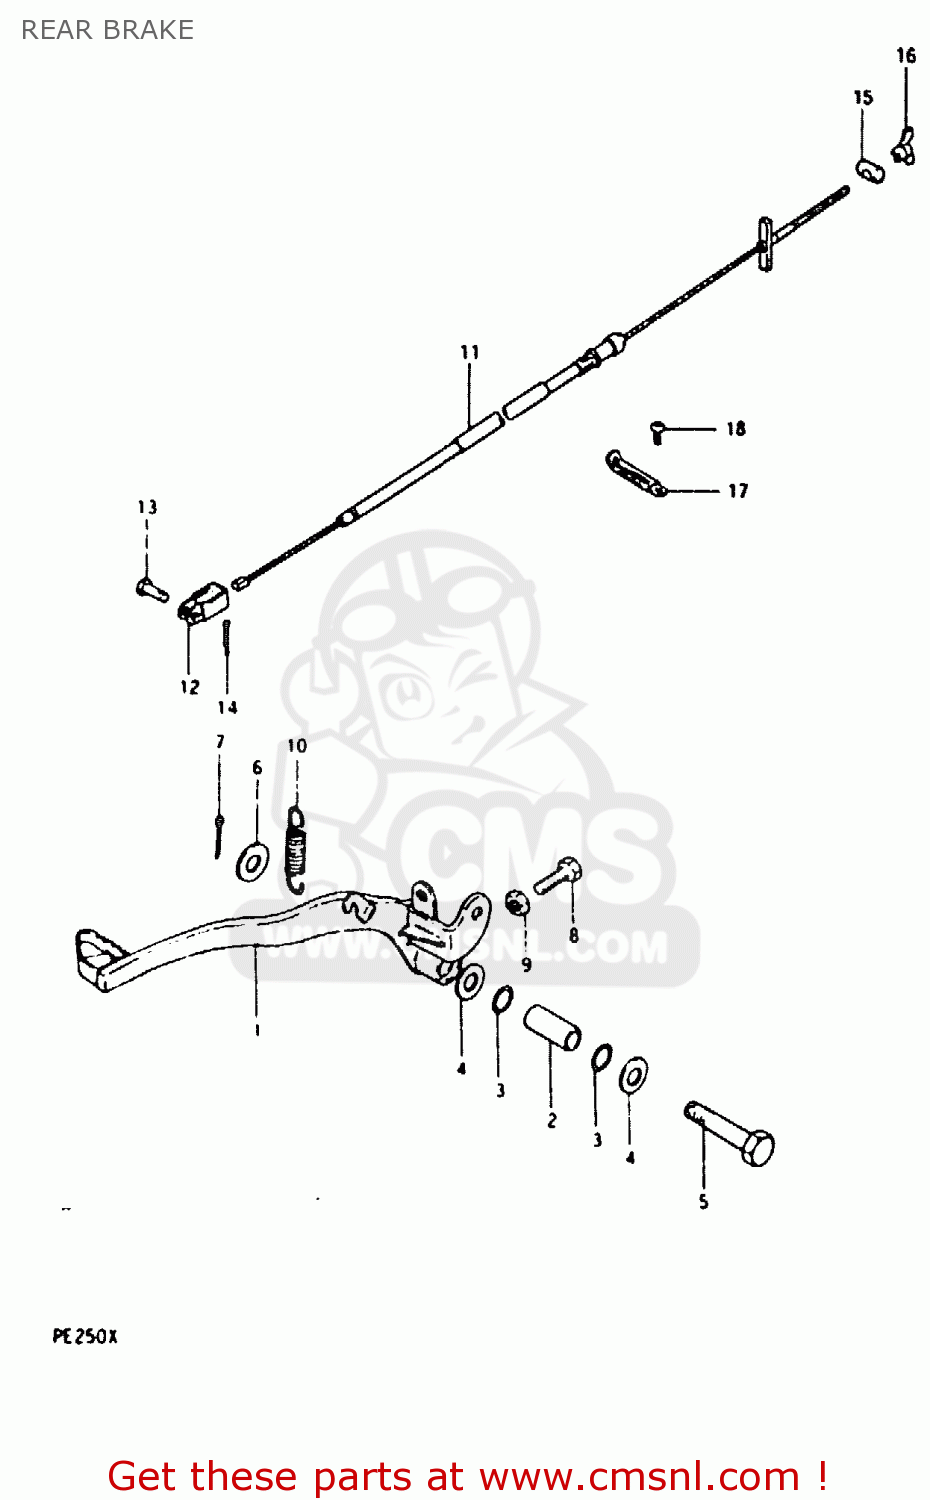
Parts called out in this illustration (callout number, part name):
1	PEDAL,BRAKE
2	SPACER (8X10X22)
3	O-RING (D:1.5 ID:10)
4	WASHER
5	BOLT 8X43.5
6	WASHER
7	PIN 20X20
8	BOLT 6X25
9	NUT
10	SPRING
11	CABLE,RR BRAKE
12	HOOK,REAR BRAKE PEDAL
13	PIN(L:13)
14	PIN
15	PIN
16	NUT
17	CLAMP
18	SCREW,6X6
